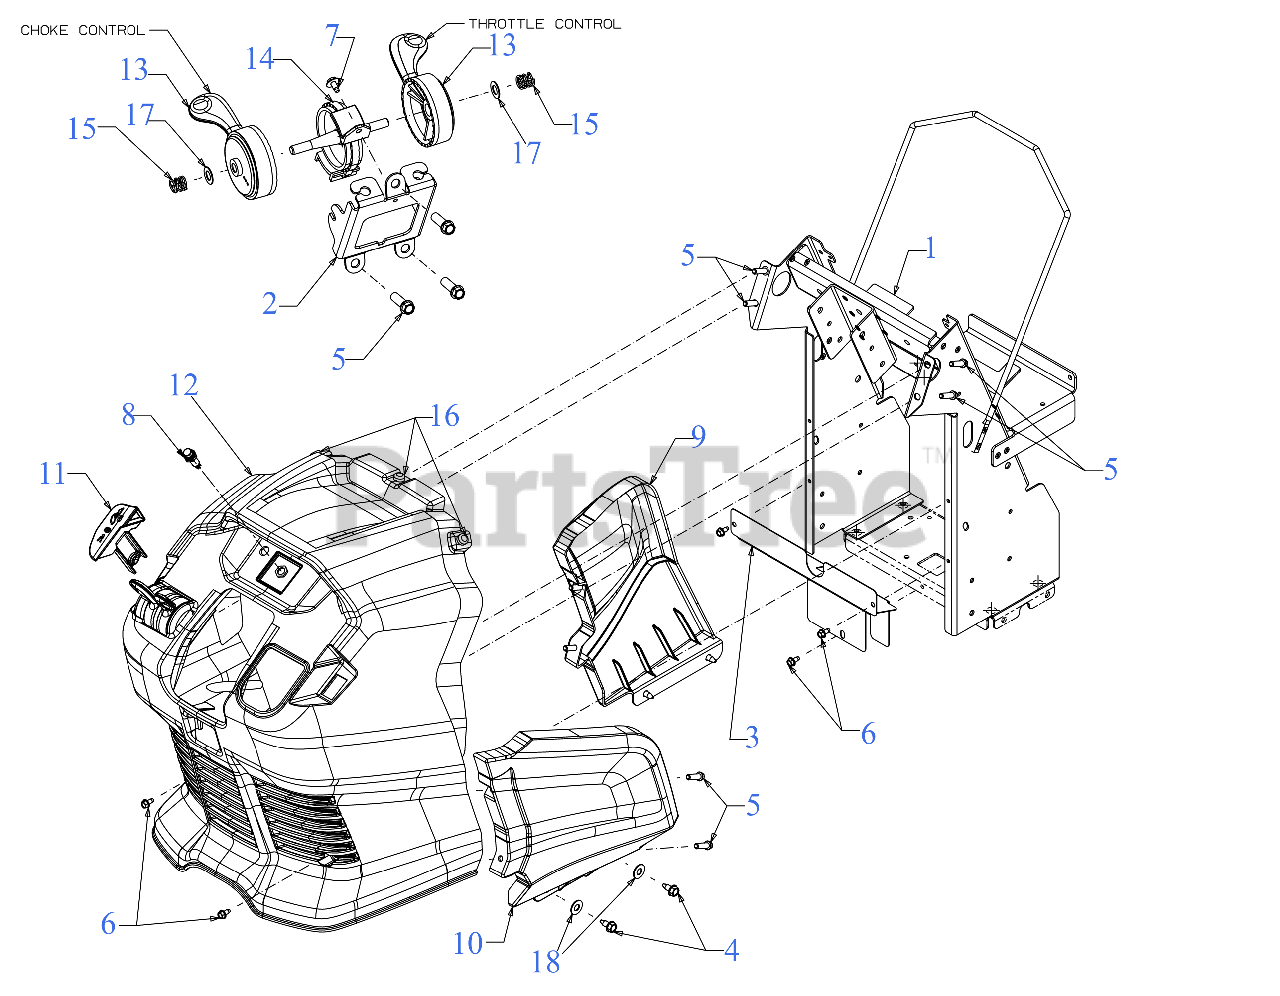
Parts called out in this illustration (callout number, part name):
3	ENGINE SHIELD
4	SCREW 5/16-18 x .750
5	SCREW 5/16-14 x 1
6	SCREW 1/4-20 X.500
7	SCREW #10-16 x .375
8	INDICATOR LED LIGHT-YELLOW
9	DASH PANEL LOWER (LH)
10	DASH PANEL LOWER (RH)
11	CRUISE/PARK BRAKE LEVER
12	DASH PANEL
13	THROTTLE/CHOKE CONTROL LEVER
14	THROTTLE/CHOKE INDEX DISC
15	COMPRESSION SPRING
16	BUMPER, .62 DIA x .3
17	FLAT WASHER .344 ID x .62 OD x .033
18	FLAT WASHER.40 ID
